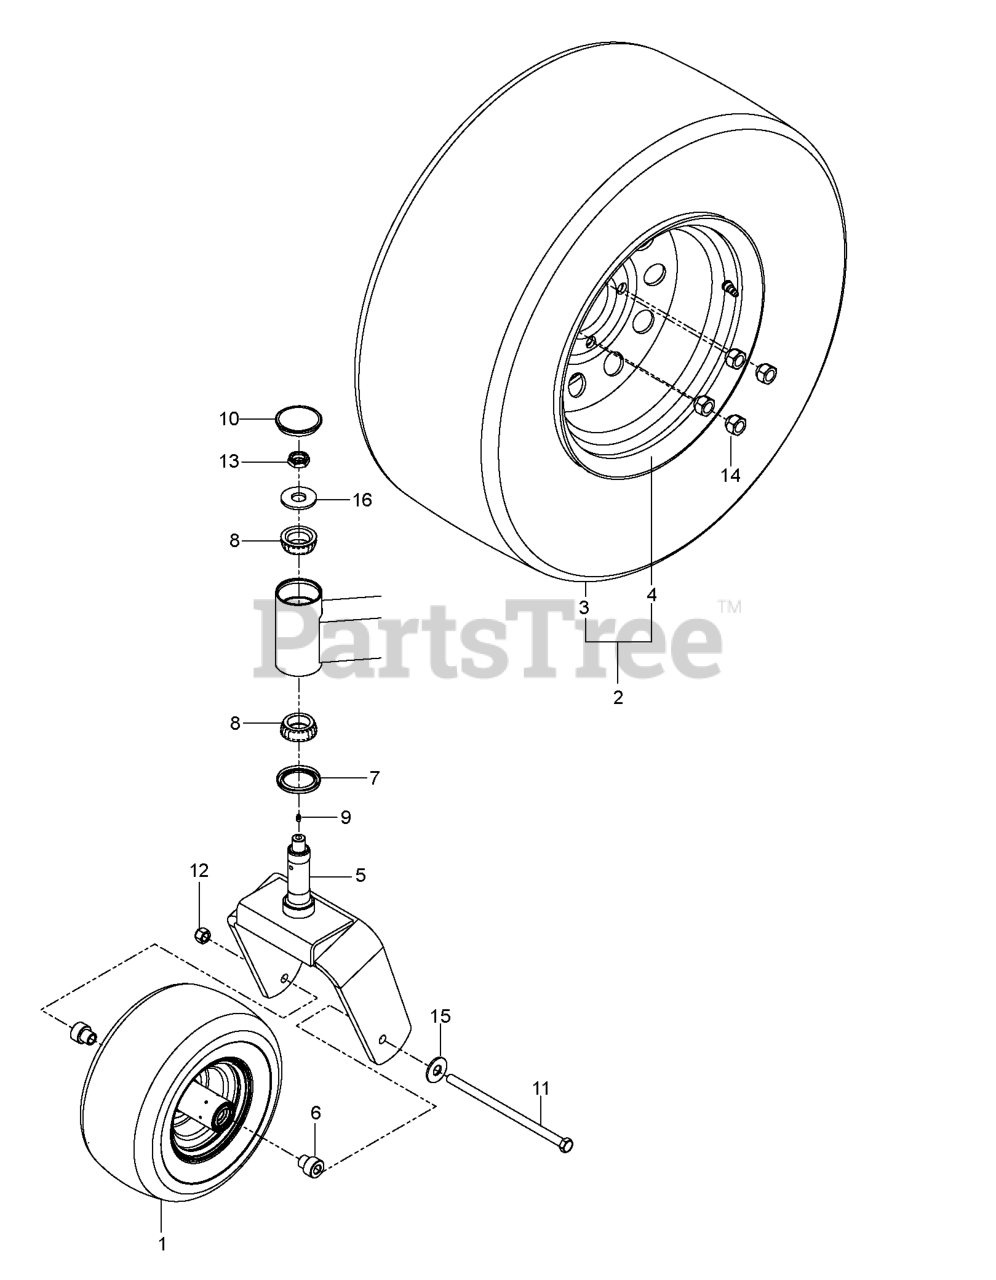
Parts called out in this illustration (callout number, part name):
1	TIRE, 13 X 6.5-6 NO FLAT
2	WHEEL/TIRE.ASM SILV 23X10.5-12
3	TIRE.TURF.MASTER.23X10.5-12
4	RIM, 12 X 8.5, 1.125" NEG OS
5	FORK.CASTER.ORANGE
6	AXLE SPACER
7	SEAL, BEARING
8	CONE, LM67048
9	ZERK
11	HEX SCREW 1/2-13 X 9.5 GR5
12	NUT, 1/2-13 HEX FLG NYLOC ZD
13	NUT, 3/4-16 HEX THIN NYLOC ZD
14	LUG NUT 1/2F
15	WASHER 1/2" FLAT
16	WASHER, 3/4 HARDENED
